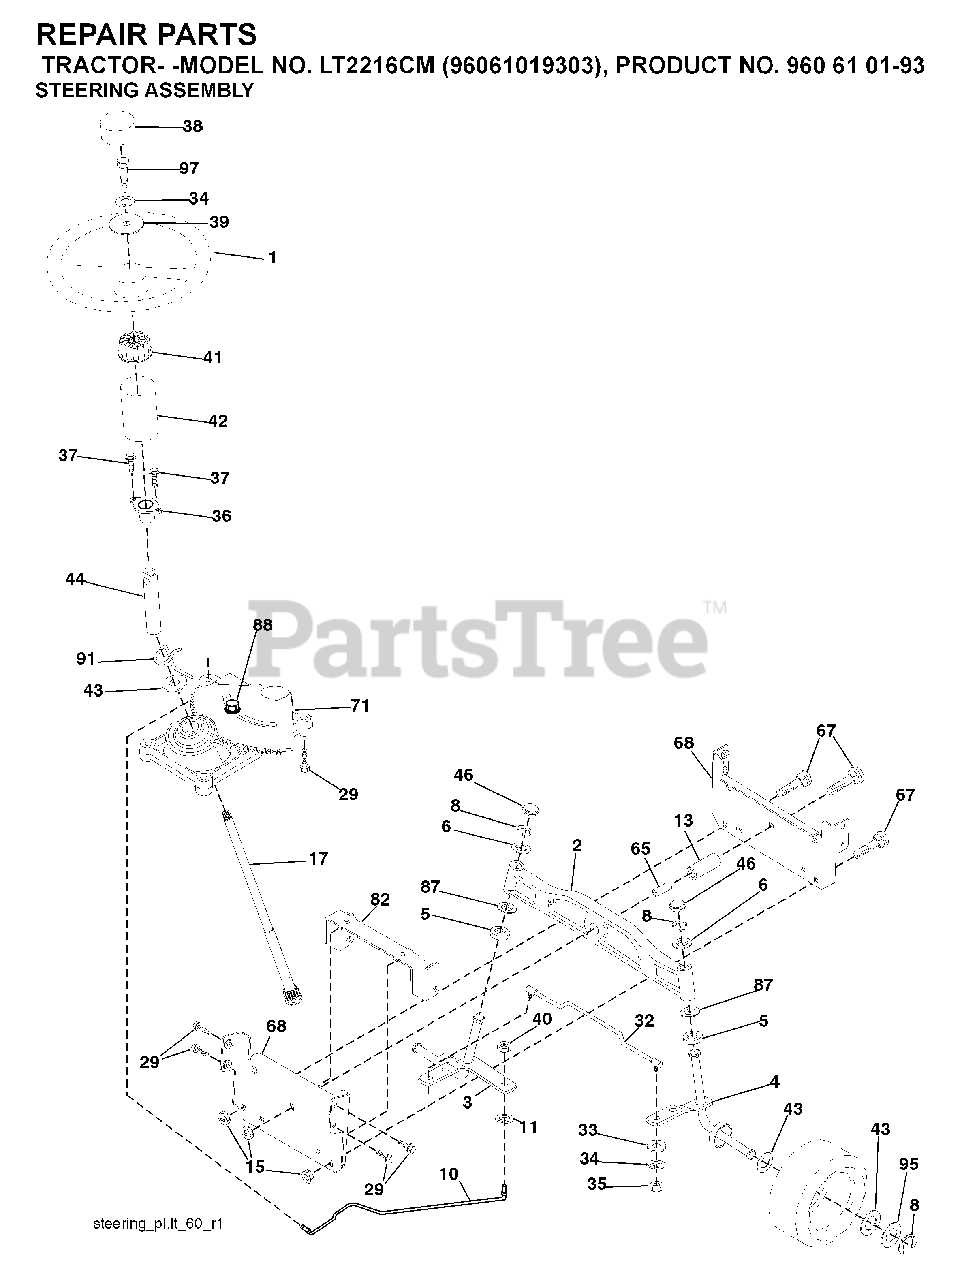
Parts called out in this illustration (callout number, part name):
1	WHEEL.STEERING.PREM.2.BLK
2	AXLE ASSY FRONT
3	SPINDLE.ASM.LH.15"TIRES
4	SPINDLE.ASM.RH.15"TIRES
8	RING CLIP
10	DRAGLINK.15".TIRES.2001
11	WASHER, LOCK 3/8
13	TUBE, PIVOT AXLE
15	NUT
17	SHAFT STEERING SPLINE
29	SCREW, 3/8-16X3/4
32	ROD.ASM.TIE.BALL.JOINT.NOVAN
33	WASHER M
34	LOCKWASHER
35	NUT, CROWNLOCK
36	BUSHING, STEERING
38	INSERT.CAP.STRG.WH.BLACK
39	WASHER.11/32
40	NUT CROWNLOCK 3/8-24
41	ADAPTER, WHEEL STNG..
42	BOOT.STEERING.SHAFT.BLACK
44	SHAFT.EXTEN.STRG.SPLINE
46	CAP.SPINDLE
65	SPACER BRACE AXLE
67	BOLT CARRIAGE
68	BRACE.AXLE.15"TIRES
71	STEERING ASM
82	BRACKET.SUSP.CHASSIS.FRONT.15
87	WASHER, FLAT .781 X 1 1/2"
88	BOLT, SHOULDER 7/16-20
91	CLIP.STEERING
95	WASHER.HARDENED
